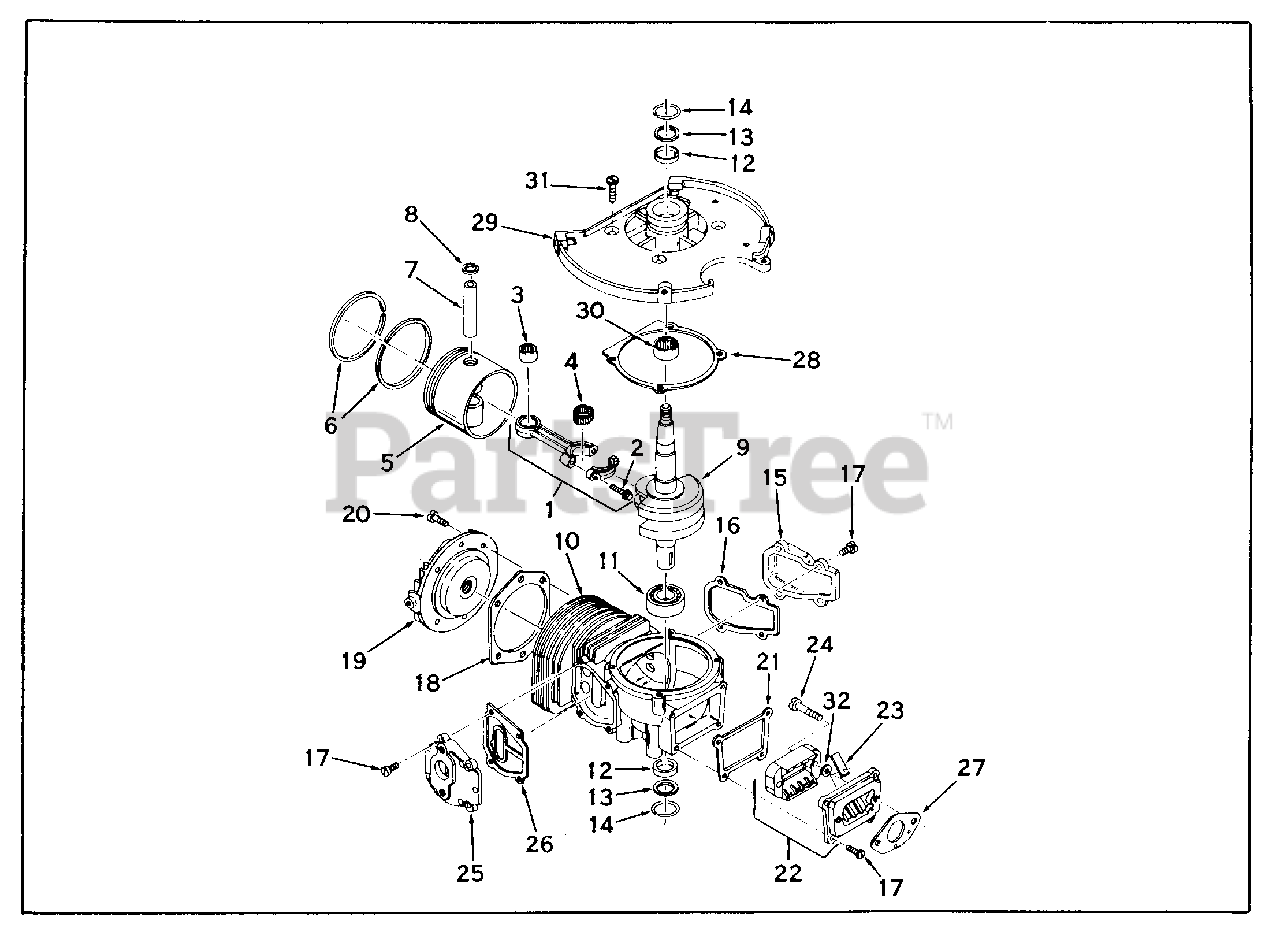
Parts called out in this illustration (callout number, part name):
1	"Rod Assy., Connecting Incl. 2, 3 & 4
2	Screw, Connecting rod
3	Bearing, Cartridge
4	Bearing, Needle (Set of 33)
5	Piston
6	Ring Set, Piston
7	Pin, Piston
8	Ring, Piston pin retaining
9	Crankshaft
10	Cylinder (Incl. 11 thru 14)
11	Bearing, Ball
12	Seal, Crankshaft
13	Retainer, Crankshaft seal
14	Spring, Crankshaft seal retainer
15	Plate, Cover
16	Gasket, Cover plate
17	Screw, 10-24 x 1/2"
18	Gasket, Cylinder head
19	Head, Cylinder
20	Screw, Torx T-30, 1/4-20 x 3/4"
21	Gasket, Reed & cover plate
22	Plate Assy., Reed & cover Incl. 23 &2 4
24	Screw, 1/4-28 x 1-1/4"
25	Cover, Adapter
26	Gasket, Adapter cover
27	Gasket, Carburetor
28	Gasket, Shroud base
29	Shroud Base (Incl. 12, 13, 14 & 30)
30	Bearing, Needle
31	Screw, 1/4-20 x 5/8"
